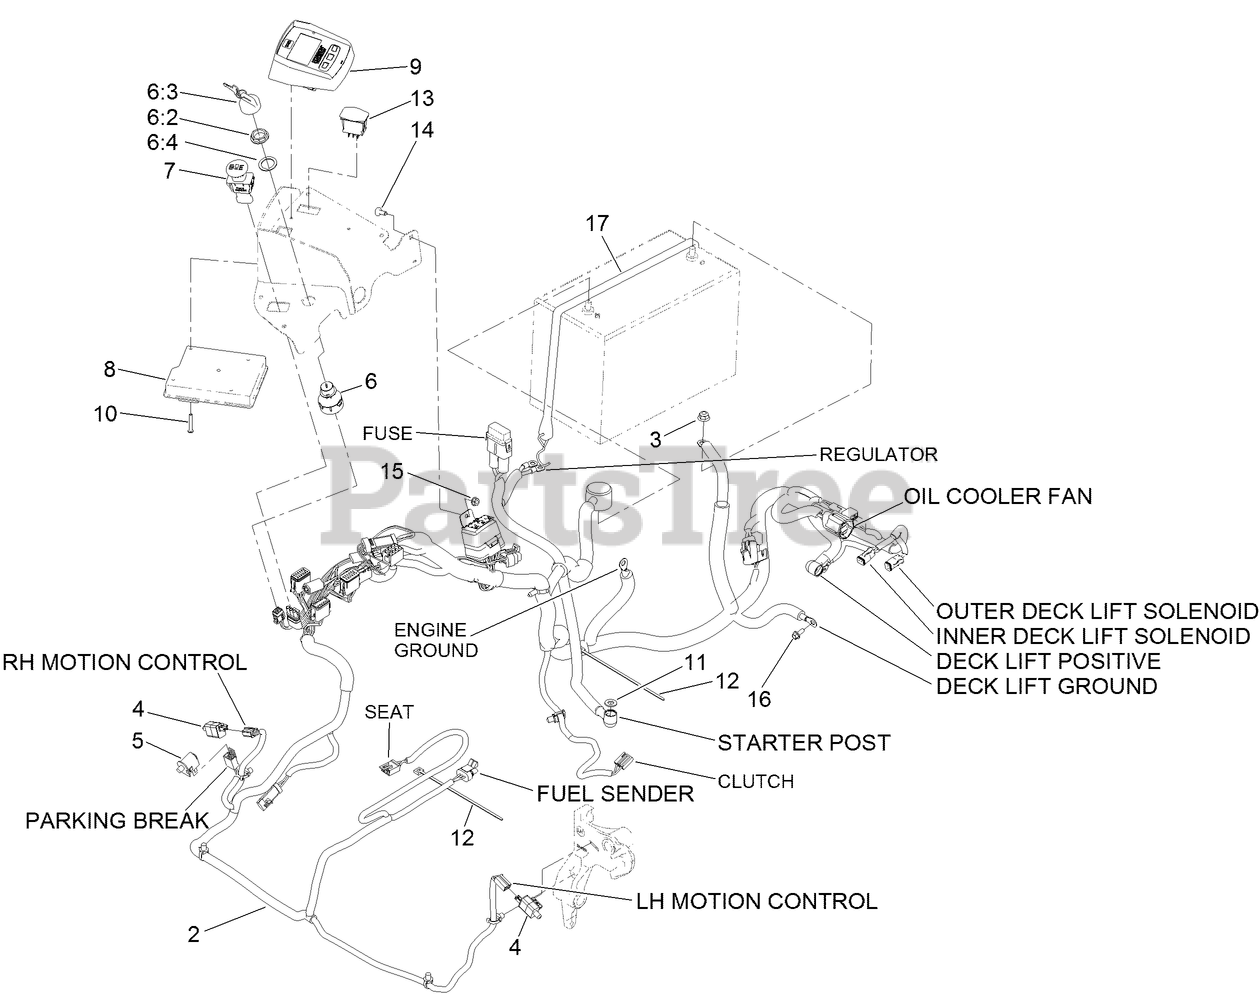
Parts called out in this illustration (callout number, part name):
2	HARNESS-WIRE
3	NUT-HF, NI
4	SWITCH
5	SWITCH-BAIL
6	IGNITION SWITCH ASM
6:2	NUT-MOUNTING
6:3	IGNITION KEY SET
6:4	WASHER-BACKUP
7	SWITCH-PTO, SEALED
8	MODULE-MCU
9	MODULE-HORIZON
10	SCREW-PPH
11	WASHER-FLAT
12	TIE-CABLE
13	SWITCH
14	BOLT-CARR
15	NUT-HF
16	SCREW-HHF
